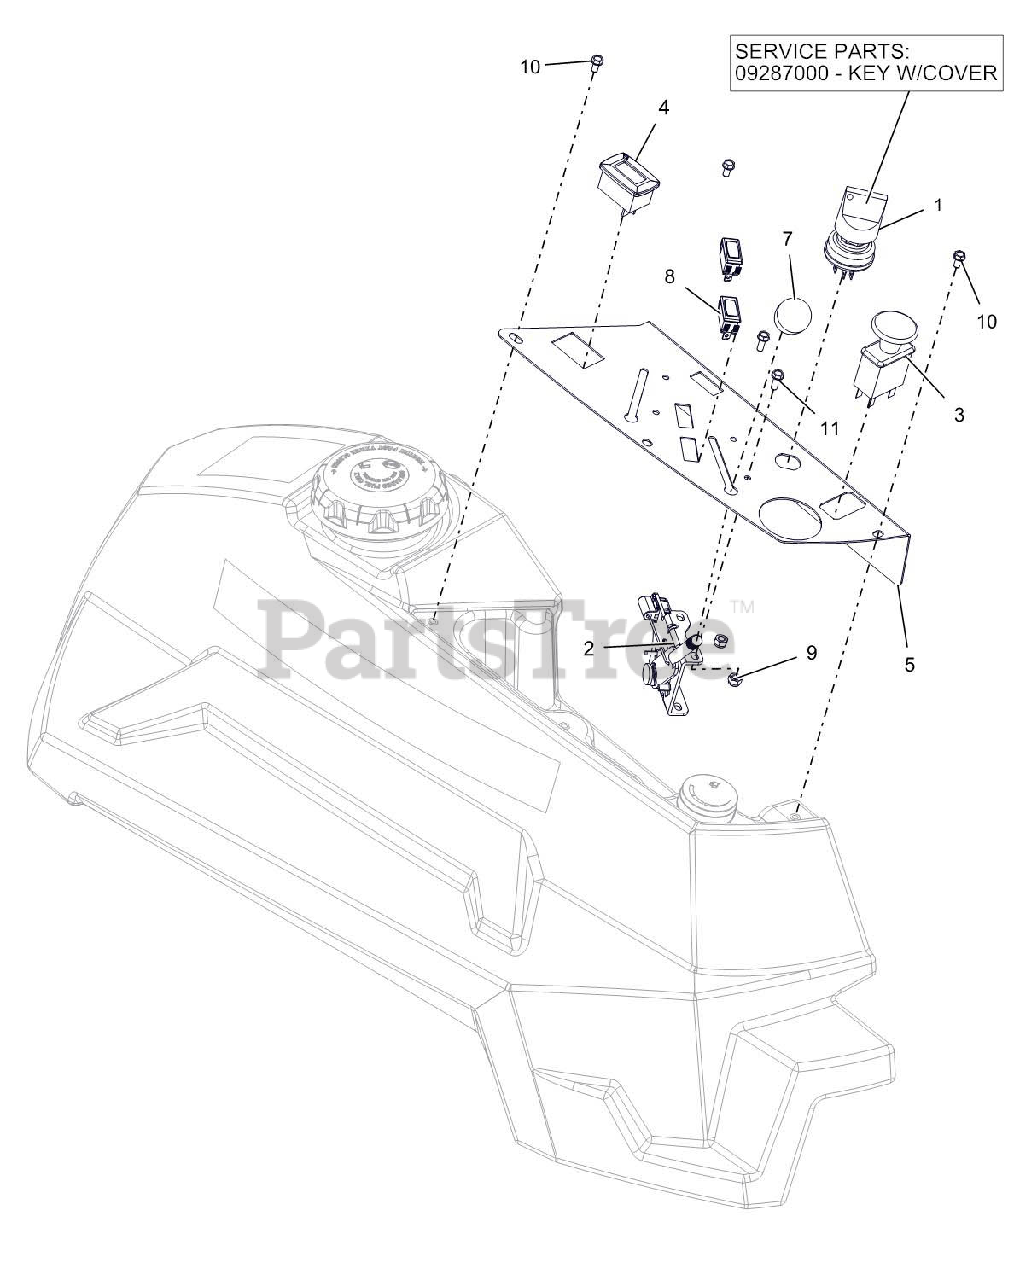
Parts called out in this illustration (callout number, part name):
1	KEY, W/ SHIELD
1	SWITCH, IGNITION
2	CABLE, PRO-CTRL 43.00"
3	SWITCH, CLUTCH
4	METER, HOUR W/MAINTENANCE
5	PT400 CONTROL PANEL - RED
7	KNOB-CONTROL-BLACK .38-16X.50
8	LIGHT,INDICATOR
9	@NUT-LK-NYL 10-24 W/INSRT YWZC
10	SCR-MCH 10-24X.38 HWHSTAINLESS
11	@SCR-MCH 10-24X.50 HWH YWZC
